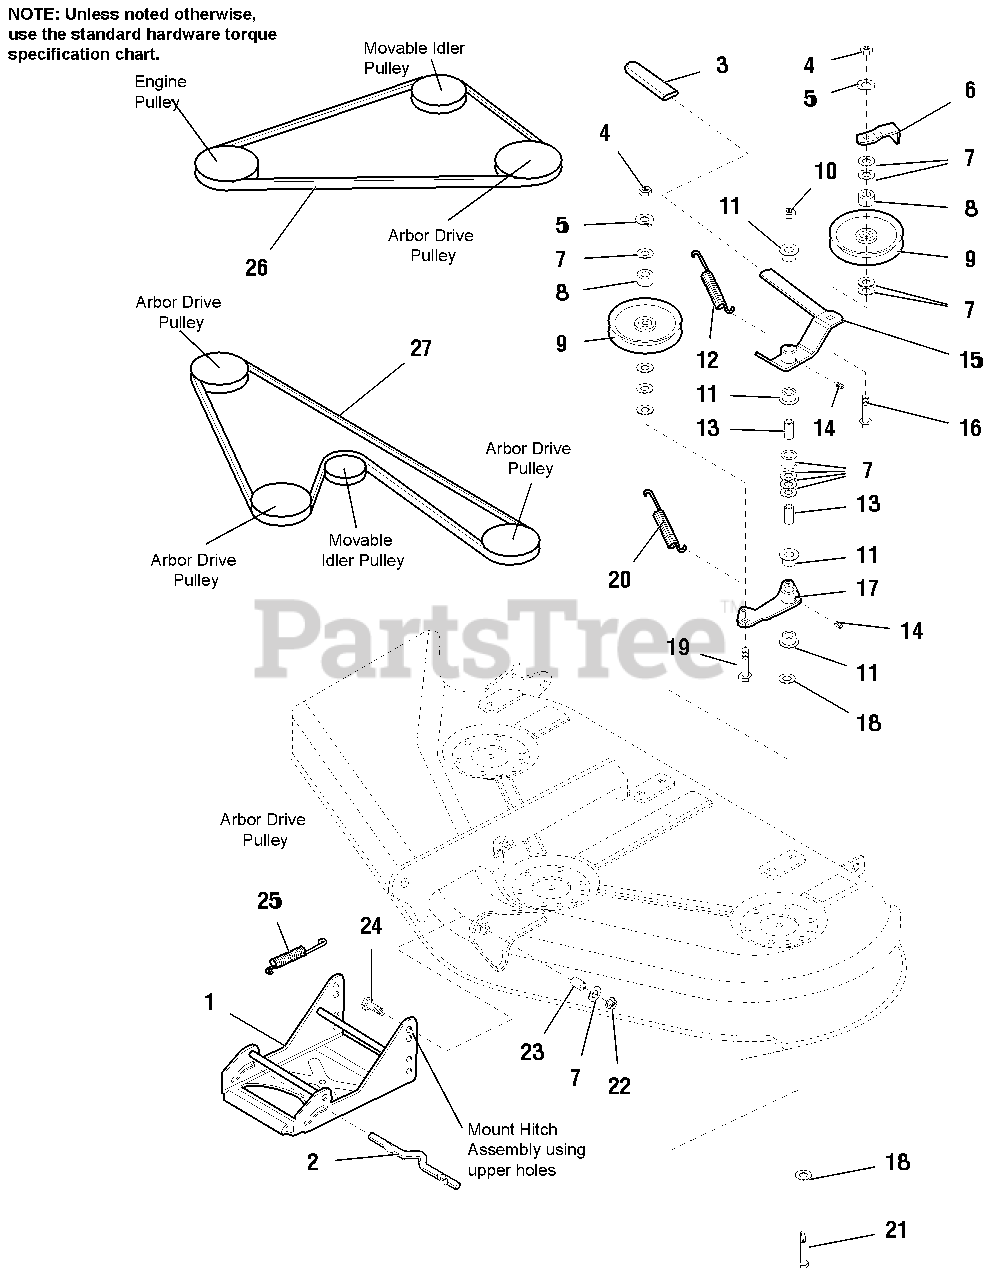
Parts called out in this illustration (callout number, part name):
1	HITCH ASSEMBLY
2	ROD, Latch
3	GRIP, Lever
4	NUT, Hex, 3/8-16
5	LOCKWASHER, 3/8
6	BELT STOP, Idler
7	WASHER, Plain, 13/32
8	SPACER
9	PULLEY, Idler (Includes Ref. No. 8)
10	NUT, Hex Flange, 2-Way Lock, 3/8-16
11	BUSHING
12	SPRING
13	SPACER
14	FITTING, Grease
15	LEVER ASSEMBLY, Idler (Includes Ref. Nos. 11 & 14)
16	CARRIAGE BOLT, 3/8-16 x 2
17	LEVER ASSEMBLY, Idler Arm (Includes Ref. Nos. 11 & 14)
18	WASHER, 3/8
19	CARRIAGE BOLT, 3/8-16 x 1-1/2
20	SPRING
21	CAPSCREW, Hex Head, 3/8-16 x 3-1/2
22	NUT, Hex Nylon Lock, 3/8-16
23	SPACER
24	CAPSCREW, Hex Head, 3/8-16 x 1-1/2
25	SPRING
26	V-BELT, Mower Drive, 44" Deck
26	V-BELT, Mower Drive, 50" Deck
27	V-BELT, Arbor Drive, 44" Deck
27	V-BELT, Arbor Drive., 50" Deck
